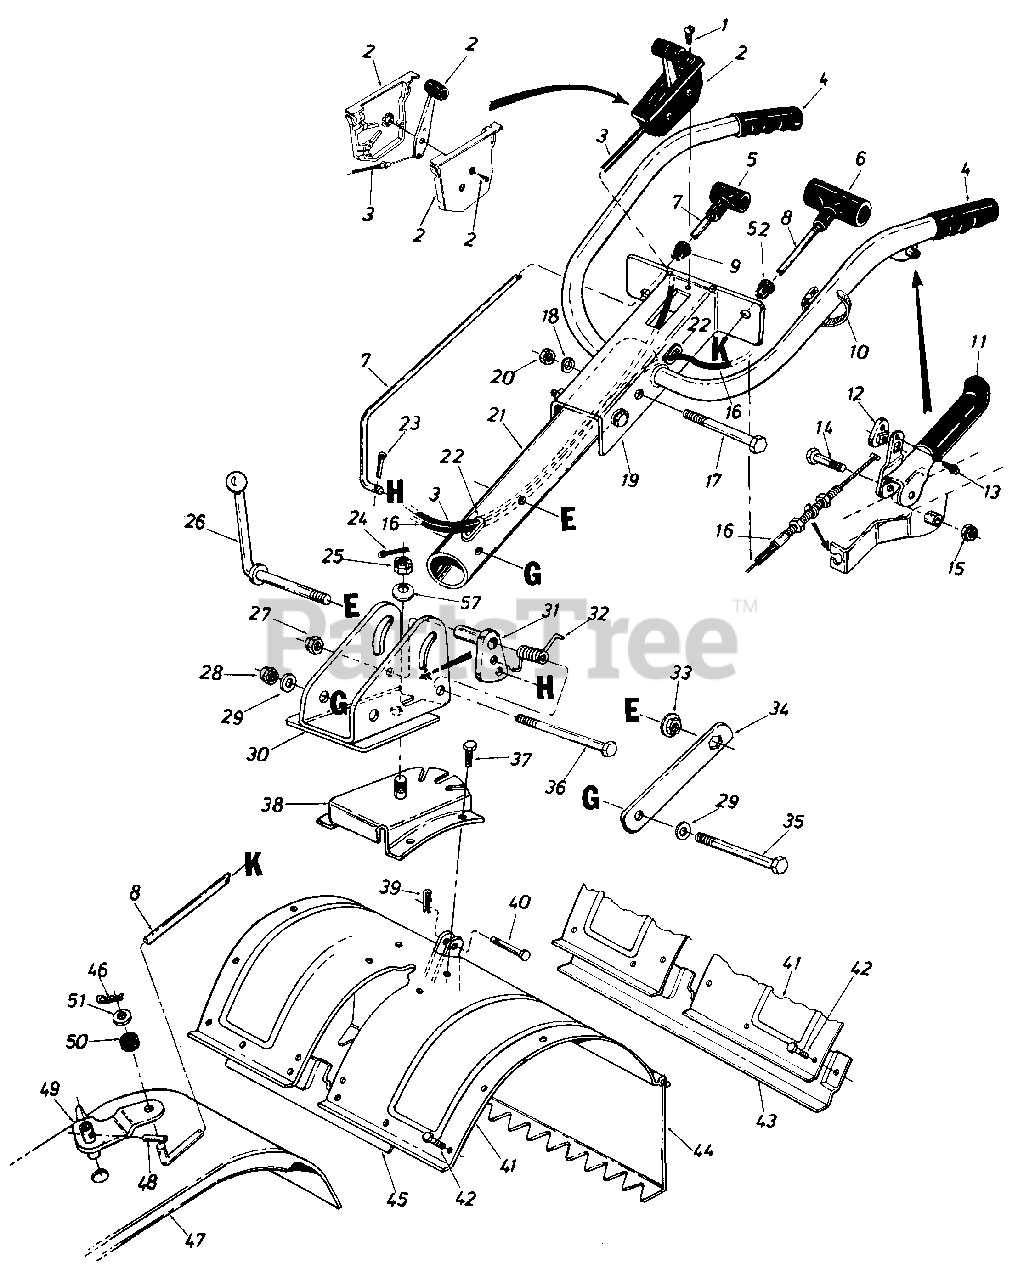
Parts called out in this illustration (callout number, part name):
1	Truss Mach. AB-Tap. Scr. #1O x .50" Lg.
2	Throttle Control Box Ass'y.
3	Throttle Control Wire
4	Handle Grip
5	Small "T" Knob
6	Large"T" Knob
7	Clutch Rod
8	Control Rod 37" Lg.
9	Snap On Bushing 3/8" Dia.
10	Cable Tie-Self Clinching
11	Clutch Grip Ass'y.-L.H.
12	Barrel Cable Hold Down
13	Hex B-Tap Scr. #10 x .441" Lg.
14	Hex Bolt 318-16 x 2.0" Lg.*
15	Hex Cent. L-Nut 3/8-16 Thd.
16	Clutch Control Cable 53" Lg.
17	Hex Bolt 3/8-16 x 3.00" Lg.
18	L-Wash. 3/8" I.D.-H.D.
19	Handle Ass'y.
20	Hex Nut 3/8-16 Thd.
23	Cotter Pin 3/32" Dia. x .75" Lg.*
24	Cotter Pin 3/32" Dia. x 1.25" Lg.*
25	Hex Slotted Nut 5/8-18 Thd.
26	Handle Adj. Crank
27	Hex Cent. L-Nut 3/8-16 Thd.
28	Hex Nut 3/8-16 Thd.*
29	Bell-Wash. .400" I.D. x 37" O.D.
30	Handle Pivot Bracket
31	Positioner Crank Ass'y.
32	Spring Handle Adj. (Torsion)
33	Hex Flange Nut 3/8-24 Thd.
34	Bracket Hex Nut Retainer
35	Hex Bolt 3/8-16 x 3.25" Lg. *
36	Hex Bolt 3/8-16 x 3.00" Lg.* Gr. 8
37	Hex Bolt 3/8-16 x .75" Lg.
40	Clevis Pin .375" Dia.
43	Bracket Reinforcement-18"
46	Intern. Cotter Pin 5/16" Dia.
47	Shift Cover
48	Spring Roll Pin 3/16" Dia. x 1.00" Lg
49	Shifting Crank Ass'y. D x 2.05
50	Rubber Washer .33" I.D. x .87" O.D.
51	Fl-Wash. .400" I.D. x 1.250" O.D.
52	Snap On Bushing 1/2" Dia.
57	Bell-Wash. .630" I.D. x 1.25" O.D.
